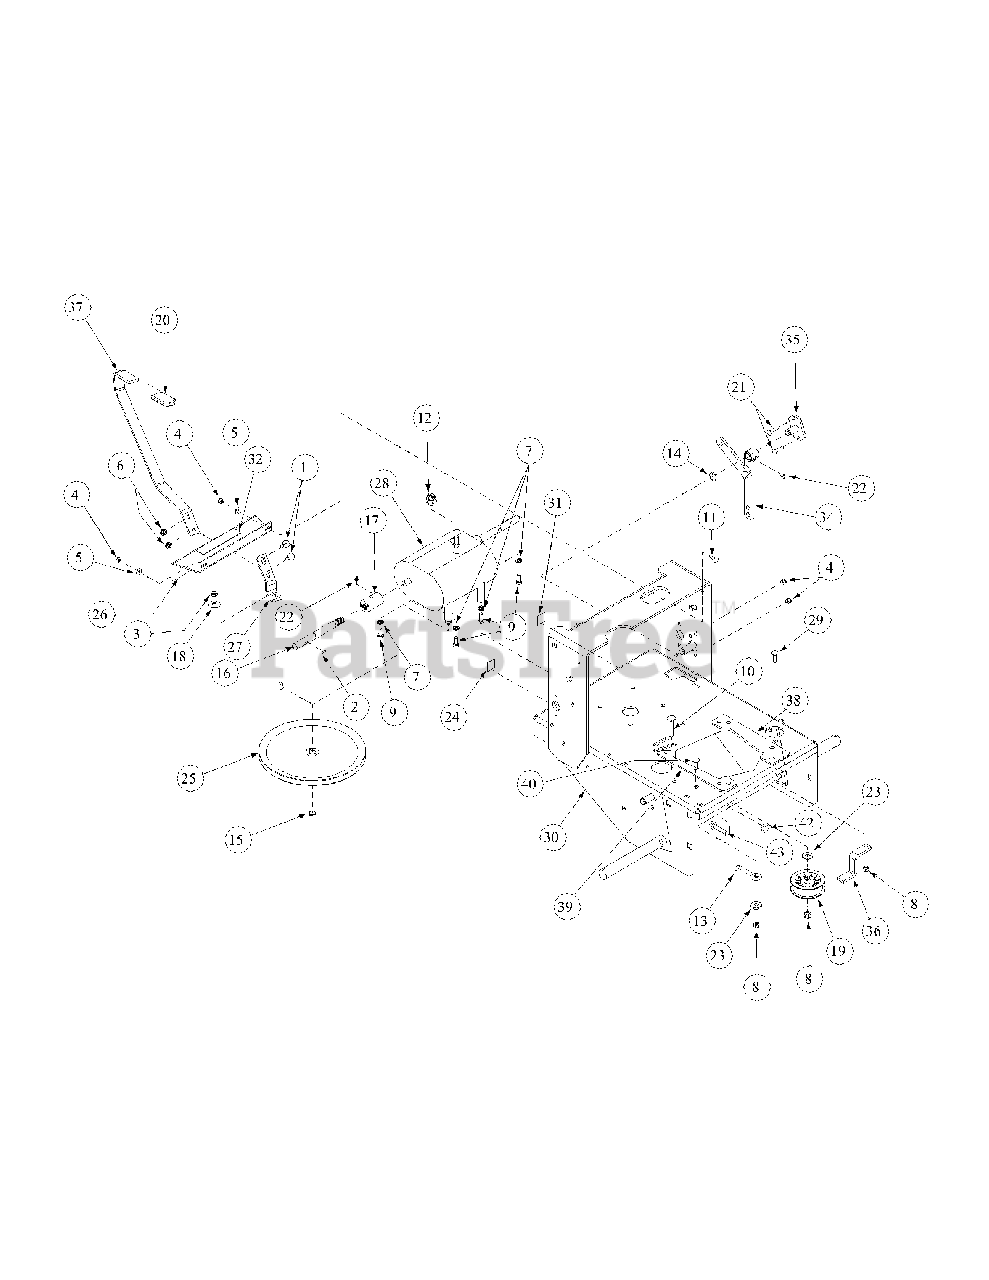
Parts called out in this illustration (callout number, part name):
1	Carriage Bolt, 5/16-18 x 1
2	Woodruff Key, 3/16 x 3/4
3	Jam Nut, Insert Lock, 3/8-24
4	Lock Nut, Nylon Insert, 1/4-20
5	Flat Washer, 1/4 Zinc
6	Nut, 5/16-18 Nylock
7	Lock Washer, 5/16 Zinc
8	Lock Nut, Nylon Insert, 3/8-16
9	Hex Cap Screw, 5/16-18 x 3/4
10	Carriage Bolt, 3/8-16 x2
11	Carriage Bolt, 1/4-20 x .750
12	Switch, WB Transmission
13	Drive Belt Guide
14	E-Ring, 5/8
15	External Retainer Ring
16	Jackshaft w/ Heavy Spline
17	Coupling w/Heavy Spline
18	Bell Washer, .39 ID x 1.13 OD x .062
19	Flat Idler Pulley w/Adapter
20	Grip, .250 x 1 x 3-1/2, Yellow
21	Carriage Bolt, 1/4-20 x 1.00
22	Grease Fitting, 1/4-28 x 3/16
23	Idler Washer
24	Decal "Made In America
25	Transmission Pulley
27	Shift Arm
28	Transmission, 5 Speed
29	Carriage Bolt, 3/8-16 x 1
30	Engine Deck Assembly
31	Label, Warning, Open Belt Drive
32	Label, Mower Instruction
34	Clutch, Bellecrank Weldment
35	Bellecrank Pivot, Weldment
36	Engine Belt Guide
38	Engine Spacer, LH
39	Engine Spacer, RH
40	Carriage Screw, 3/8-16 x 1.25
42	Hex Lock Nut, 1/4-20
43	Hex Cap Screw, 1/4-20 x 2
